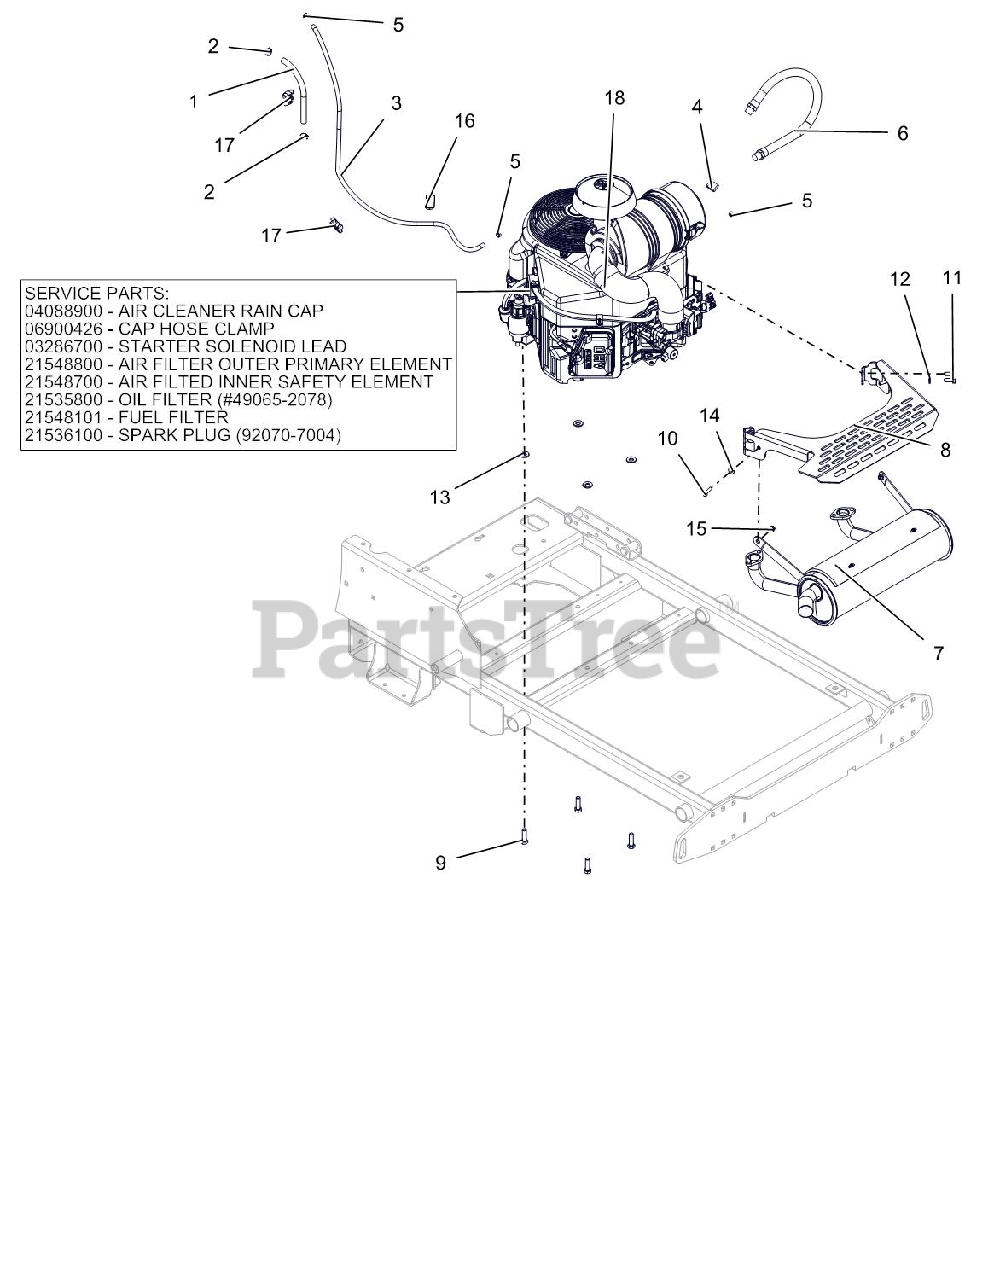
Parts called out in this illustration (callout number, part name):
1	HOSE, .25 LOW-PERM BULK GAS
2	CLAMP, FUEL LINE
3	HOSE, .188 LOW-PERM BULK GAS
4	PIPE CAP 3/8 NPT FEMALE
5	CLAMP-HOSE, SPRING .188
6	DRAIN, M20 OIL
7	EXHAUST, KAWASAKI PROSTANCE
8	SHIELD, MUFFLER
9	BLT-HEX.38-16X1.25 G5YZ NYTORQ
10	@BLT-HEX .25-20X1.00 GR5 YWZC
11	@BLT-HEX M8-1.25X20 YWZC
12	@WSHR-LK .31X.078 REG YWZC
13	WASHER, 3/8" SPRING DISC
14	@WSHR-FL-STL.281X.62X.065 YWZC
15	@NUT-LK-NYL-FLG .25-20 YWZC
16	CLAMP, COUSHIONED STEEL REV
17	CLIP, T, .38-.50
18	FILTER,OIL - KAW
18	PLUG, SPARK
18	LEAD - STARTER SOLENOID
18	CAP, KAW 11065-7025
18	CLAMP, HOSE #36 SS 1.813-2.75
18	FILTER, OUTER
18	FILTER, INNER - KAW
18	ENGINE, KAWASAKI FX691
18	FUEL FILTER-KAWASAKI FR
